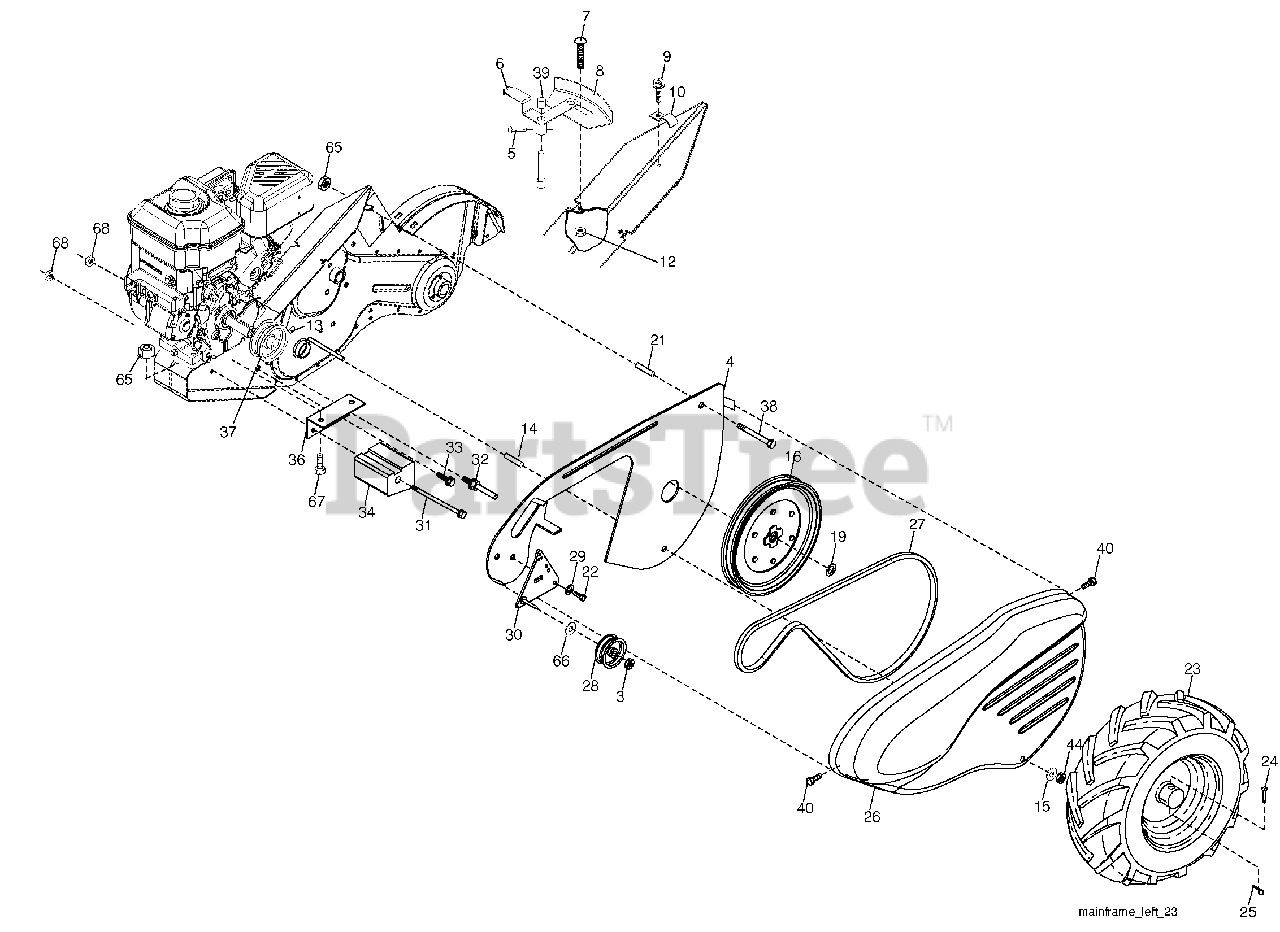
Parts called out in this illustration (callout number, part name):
3	Nut, Hex 3/8-16
4	Shield, Inner Belt Guard RT
5	Pin Spirol Flared
6	Lever, Shift
7	Bolt, Carriage 1/4-20 x 1/2 Gr. 5
8	Plate, Shift Indicator
9	Screw, Hex, Washer Head, Slotted #10-24 x 1/2
12	Nut, Keps Hex 1/4-20 unc
13	Screw, Set, Hex 5/16-18 x 3/8
14	Spacer, Split 0.327 x 0.42 x 2.09
15	Washer 11/32 x 11/16 x 16 Ga.
16	Sheave, Transmission
19	Retainer, Ring
21	Spacer, Split
22	Bolt, Fin Hex 5/16-24 unf x 1/2
24	Rivet, Drilled
25	Clip, Hairpin
26	Guard, Belt
27	Belt, V
28	Pulley, Idler
29	Ring, Klip
30	Bracket, Idler
31	Bolt, Hex 5/16-16 x 12
32	Shaft, Idler Arm
33	Bolt, Hex 3/8-16 x 1
34	Counterweight, L. H.
36	Bracket, Reinforcement, L. H.
37	Sheave, Engine
38	Bolt, Fin Hex 5/16-18 unc x 2-3/4
39	Cap, Plunger Blk
40	Screw Hex Wsh Slt #10-24 x 1/2
44	Nut Lock Hex w/Ins 5/16-18 unc PL
65	Nut Lock Hex Flange
66	Washer 13/32 x 13/16 x 12 Ga.
67	Bolt, Fin, Hex 5/16-18 unc x 1-1/2
68	Nut Keps Hex 3/8-16 unc
